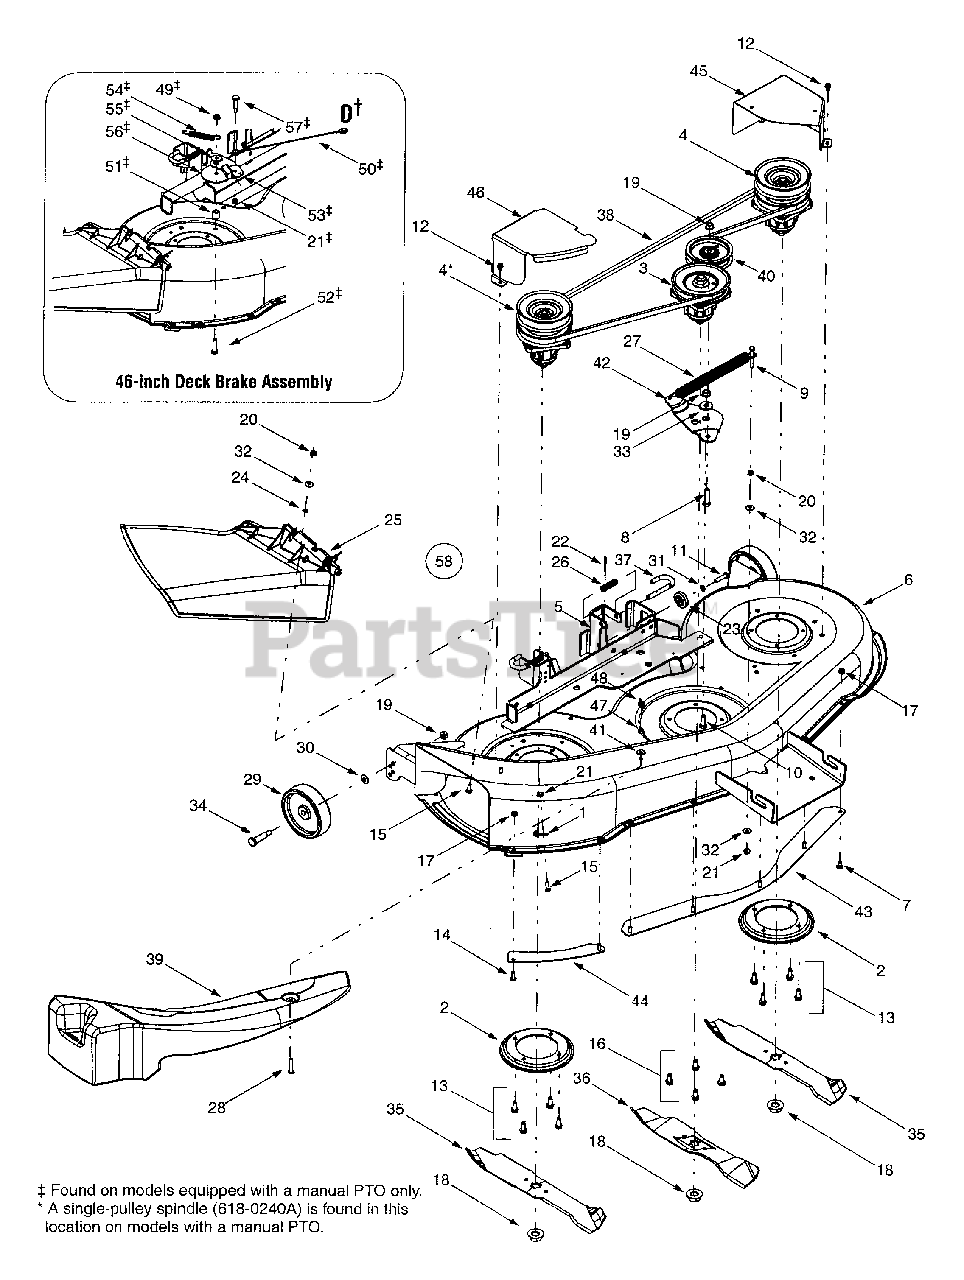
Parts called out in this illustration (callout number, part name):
1	Retainer Hook
4	Double Pulley Spindle Assembly
8	Hex Cap Screw, 3/8-16 x 1.5
9	Hex Cap Screw, 1/4-20 x 2.0
10	Hex Cap Screw, 3/8-16 x 1.0
11	Hex Cap Screw, 5/8-18 x 1.25
12	Self-tapping Screw, 1/4-20 x .5
13	Self-tapping Screw, 15/16-18 x .875
14	Hex Screw, 1/4-20 x .75
15	Hex Cap Screw, 1/4-20 x .62
16	Self-tapping Screw, 5/16-18 x .75
17	Hex Sems Nut, 1/4-20
18	Hex Flange Nut, 5/8-18
19	Flange Lock Nut, 3/8-16
20	Hex Nut, 1/4-20
21	Hex Flange Lock Nut, 1/4-20
22	Cotter Pin, 1/8 x 1.25
23	Deck Adjustment Gear
24	Push Nut. .25 x.5
25	Side Discharge Chute Assembly
26	Compression Spring, .406 x .531 x 1.75
27	Extension Spring, .91 x 7.3
28	Screw, 1/4-20 x 1.5
29	Deck Wheel, 5 x 1.38
30	Bell Washer, .401 x .87 x .063
31	Lock Washer, 5/16
32	Bell Washer, .265 x .75 x .062
33	Shoulder Spacer, .625 x 1.16
34	Shoulder Screw
35	Three-in-one Blade, Star Center, 16.28"
36	Three-in-one Blade, Star Center, 14.88"
37	Deck Release Pin
38	Deck Belt, Poly
39	Mulch Plug
40	Idler Pulley, 3.5
41	Flat Washer, .28 x .74 x .063
48	Wing Nut, 1/4-20
49	Hex Nut, 5/16-18
50	Bracket Cable, 12"
51	Spacer, .385 x .625 x .70
52	Hex Cap Screw, 5/16-18 x 1.5
53	Deck Brake Assembly
54	Extension Spring, .5 x 3.97
55	Shoulder Spacer
56	Flat Washer, .320 x 3.0 x .125
57	Shoulder Screw, .374 x 1.16
